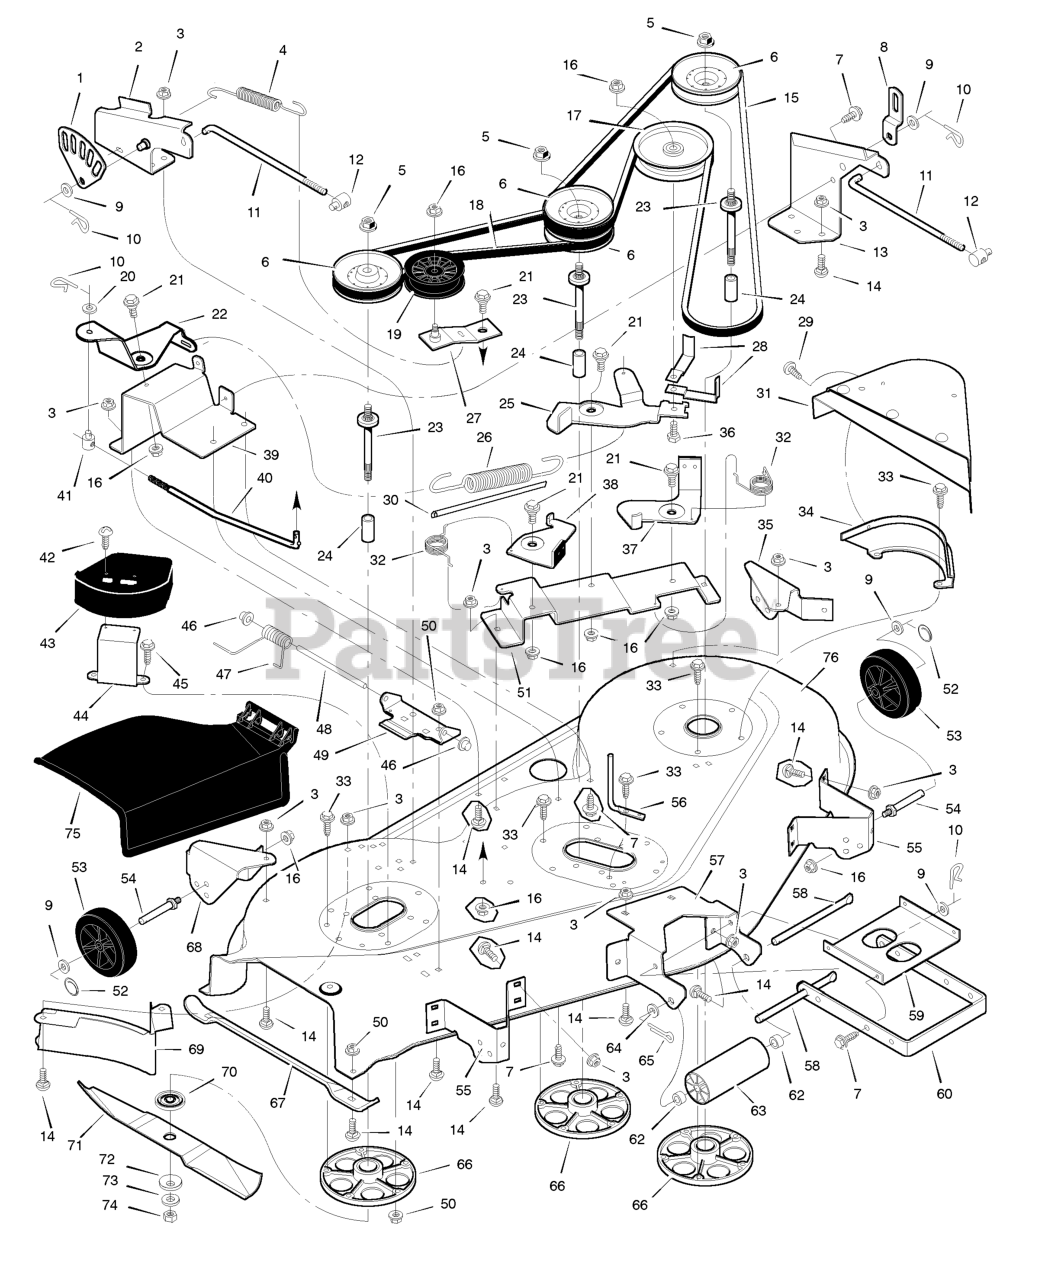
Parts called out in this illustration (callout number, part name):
1	Plate, Adjuster
2	Bracket Assembly, RH Lifter
3	Nut, Flange
4	Spring, Extension
5	Nut, Flange
6	Pulley
8	Link, Suspension
10	Hair Pin
11	Rod, Adjusting
12	NUT, Adjusting, 1/2-13
13	Bracket Assembly, LH Lifter
14	Bolt, Carriage
15	Belt, Primary Blade Drive
16	Nut, Flange
17	Pulley, Idler
18	Belt, Secondary Blade Drive
19	Pulley, Backside Idler
21	Bolt, Shoulder
22	Bellcrank, PTO
23	Shaft, Splined
25	Arm-Idler, Clutching
26	Spring, Extension
27	Arm Assembly, RH Idler
28	Guide, Belt
30	Strip, Indicator
31	Cover, LH Pulley and Extension
32	Spring, Torsion
33	Screw
34	Bracket, Pulley Cover
35	Bracket, Left Rear Gauge Wheel
36	Bolt, Idler Pulley
37	Brake Assembly, Left
38	Brake Assembly, Right
39	Bracket, Bellcrank
40	Link, PTO
41	Nut, Adjusting
42	Screw
43	Cover, Right Pulley
44	Bracket, Right Pulley Cover
45	CAPSCREW, Hex Head, 5/16-18 x 1
46	Push On Cap
47	Spring, Torsion
48	Rod, Deflector
49	Bracket, Hinge
50	Nut, Flange
51	Plate, Brake Arm
52	Ring, Locking
53	Wheel, Gauge
54	BOLT, Gauge Wheel
55	Bracket, Front Gauge Wheel
56	Guide, Belt
57	Bracket, Front Deck
58	Rod, Roller
59	Stiffener
60	Bracket, Front Suspension
65	Pin, Cotter
66	Housing, Jackshaft
67	Guard, Horn
68	Bracket, Right Rear Gauge Wheel
69	Baffle, Housing
70	Adapter, Blade
71	Blade
72	Washer, Belleville
74	Nut, Hex
75	Deflector, Chute
76	Housing, Blade
